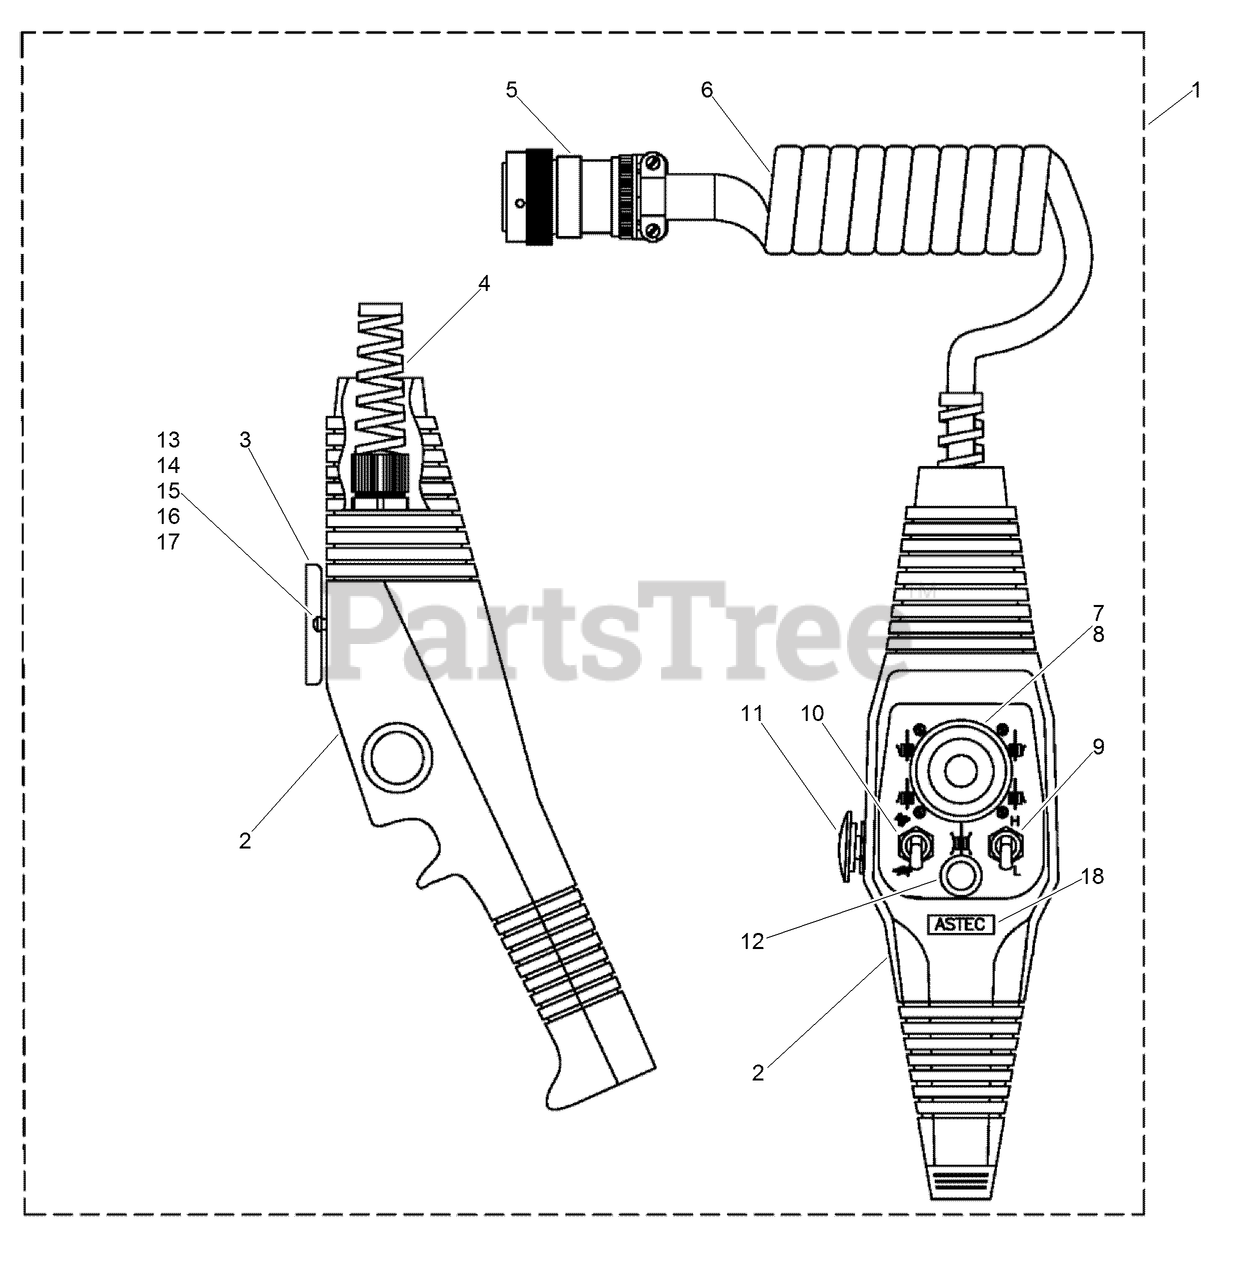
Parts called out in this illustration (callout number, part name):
1	PENDANT - Travel
2	HOUSING - Pendant
3	MAGNET - Ceramic, 2.03 Diameter x .312 H
4	CORD GRIP - with Spiral, .39-.55, Black
5	PLUG - Male, with Clamp, 18-14
6	CORD - Control, Retract 24 inch/10Foot
7	JOYSTICK - Travel
8	CONNECTOR - 8 Pin Ribbon
9	SWITCH - Toggle, Mini, Off-None-On
10	SWITCH - Toggle, Mini, (On)-Off-(On)
11	PUSHBUTTON, Red Mushroom, Momentary
12	PUSHBUTTON, Raised, Normally Open
13	NUT - Hex, #10-32, 303 Stainless Steel
14	WASHER - Flat, #10, 303 Stainless Steel
15	WASHER - Flat, 1/4 inch Stainless Steel
16	WASHER - Lock, Split Type, No. 10
17	SCREW - Machine, Slotted Pan Head
18	OVERLAY - 32GB9810 - Astec Logo
